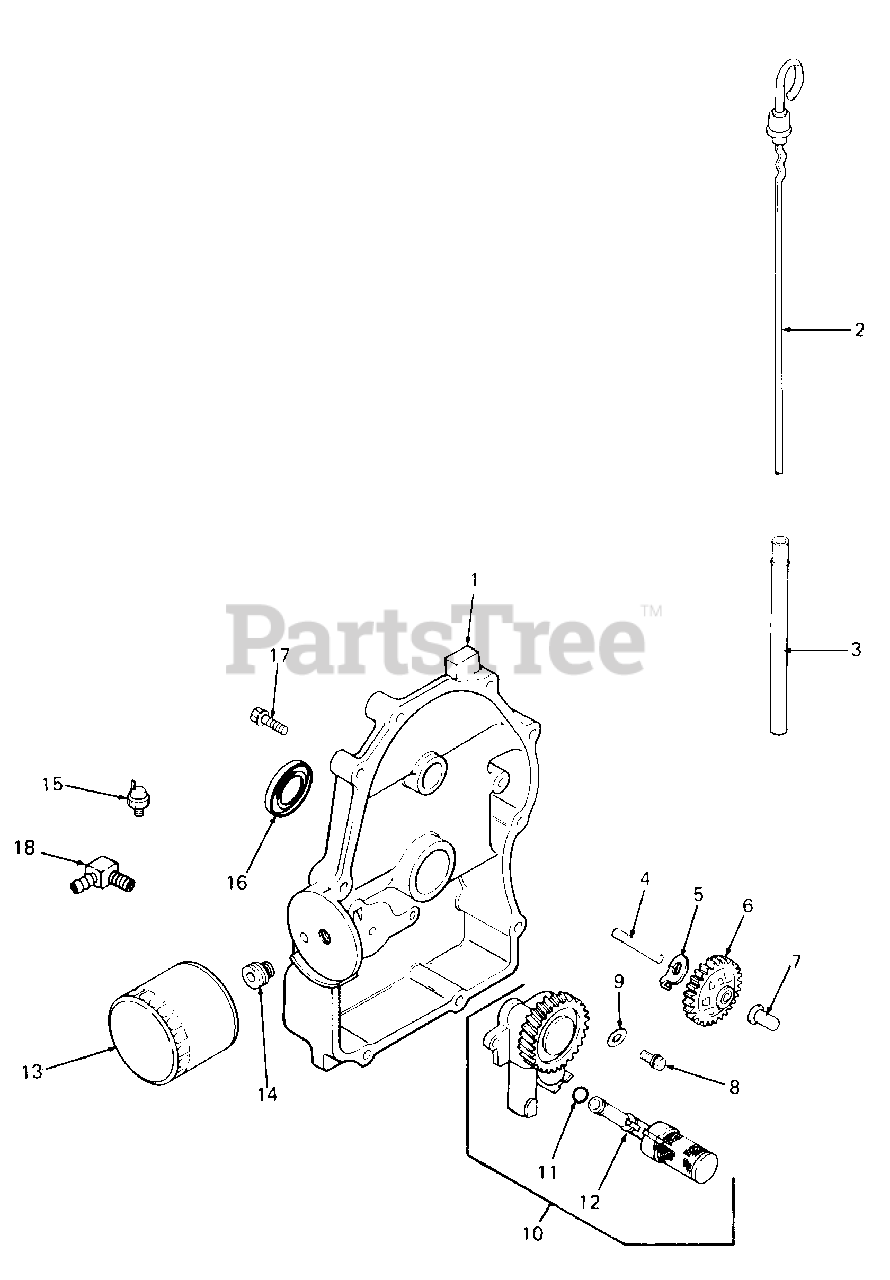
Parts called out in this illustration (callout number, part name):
1	Plate, Closure
2	Dipstick
3	Tube, Dipstick
4	Shaft, Governor Gear
5	Tab, Locking
6	Governor Gear Assembly
7	Pin, Governor Regulating
8	Screw
9	Washer
10	Oil Pump Assembly
11	O-Ring, Oil Pick-Up
12	Pick-Up, Oil
13	Filter, Oil
14	Adapter, Oil Filter
15	Switch, Oil Pressure
16	Seal, Oil (PTO end)
17	Screw, Closure Plate, M8 X .25 X 45
18	Connector, 90° Hose
